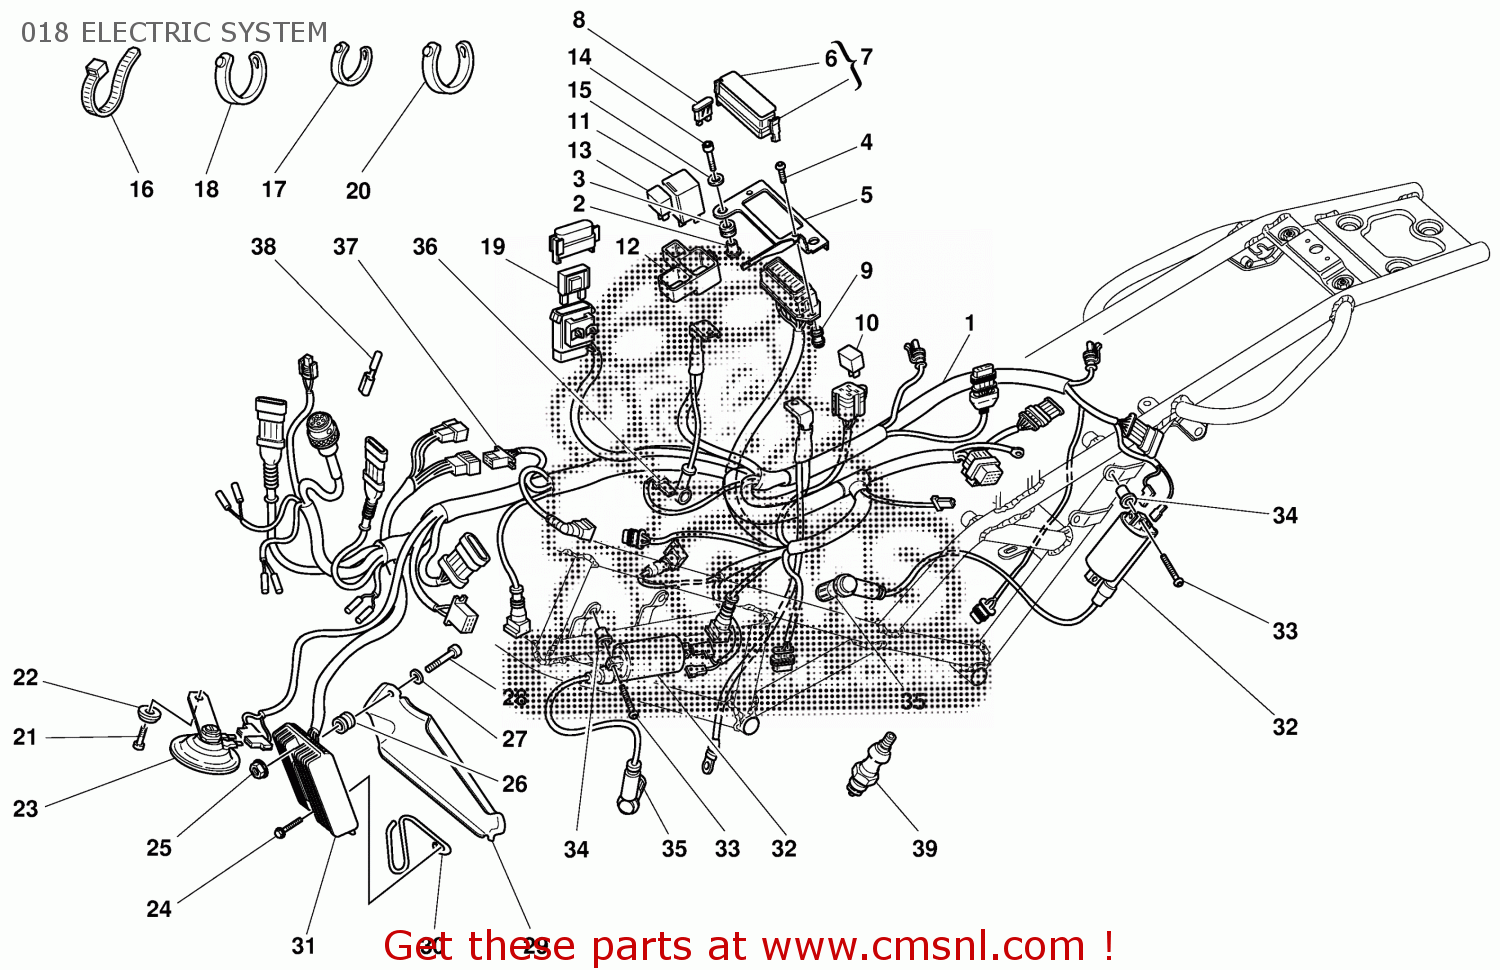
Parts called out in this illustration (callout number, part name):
1	WIRING HARNESS
2	SPACER
3	RUBBER PAD
4	SCREW
5	PLATE
6	LABEL, FUSE TABLE
7	COVER, FUSE
8	FUSE 5A
9	PIN
10	RELAY SIEMENS A-303/B1008
11	FLASHER RELAY
12	BRACKET, RELAY
13	RELAY SIEMENS A-303/B1008
14	BOLT, SOCKET HEAD M6X20
15	WASHER
16	CLAMP
17	CLAMP, RUBBER 62MM
18	CLAMP
19	FUSE 40A
20	CLAMP, RUBBER 82MM
21	SCREW M8X20
22	RETAINER
23	HORN
24	SCREW M6X20
25	NUT, FLANGED M6X1.00
26	SPACER
27	WASHER
28	SCREW
29	COVER
30	FAIRLEAD
31	VOLTAGE REGULATOR
32	IGNITION COIL
33	SCREW TBEI 5X25
34	THREADED INSERT
35	SPARK.PLUG CAP
36	CONNECTOR
37	CONNECTOR, 6 WAY
38	END SECTION
39	SPARK PLUG CHAMPION RA6HC
